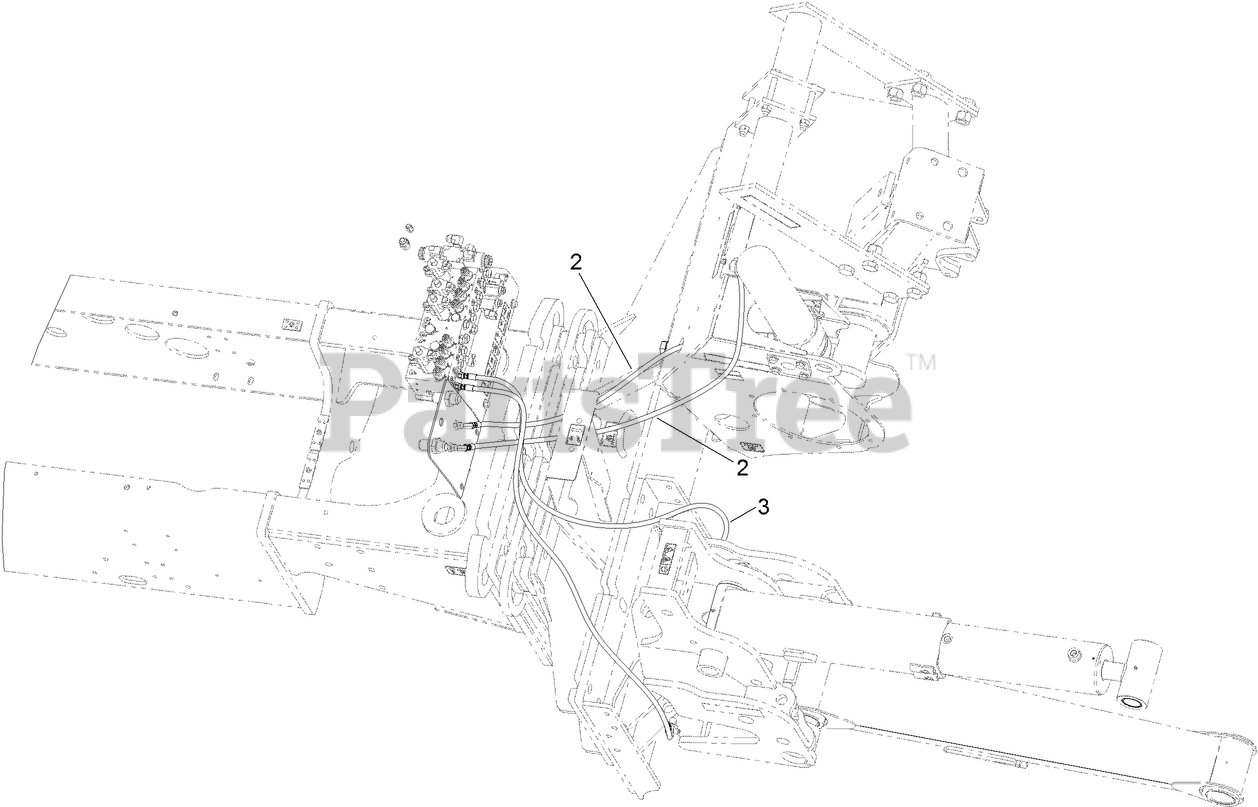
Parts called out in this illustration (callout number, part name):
2	HYD HOSE ASM
2:1	FITTING-STRAIGHT, RIGID
3	HYD HOSE ASM
